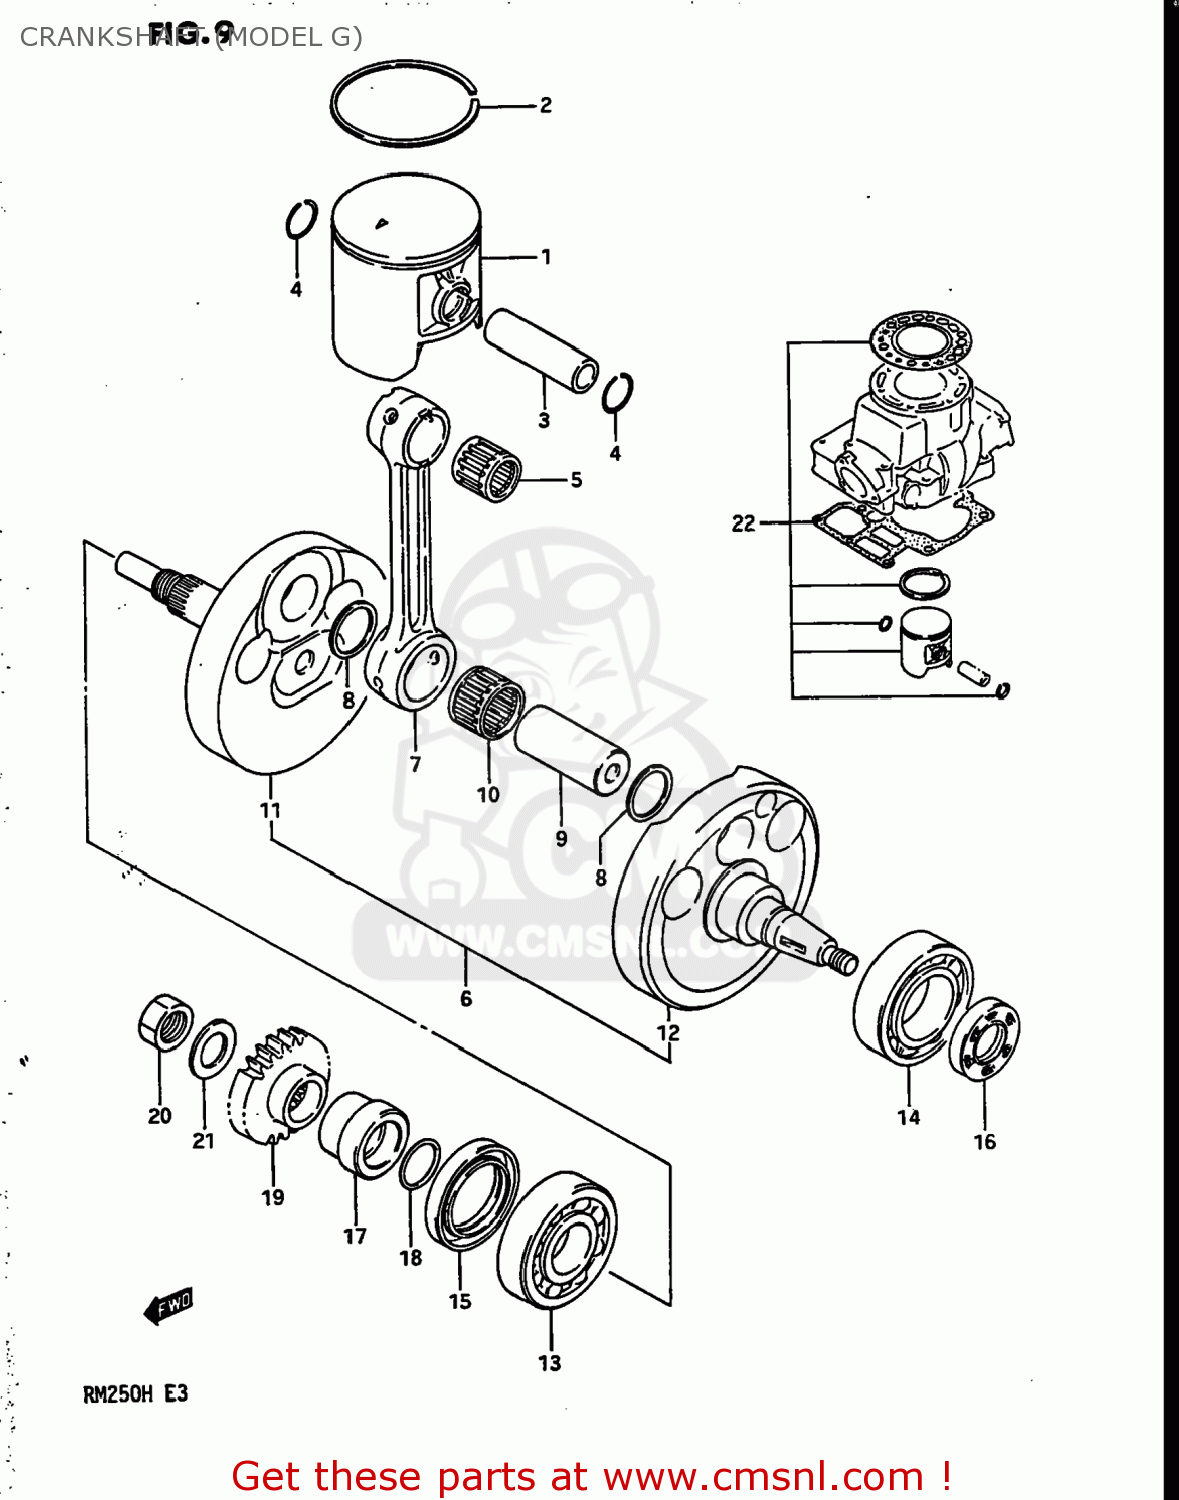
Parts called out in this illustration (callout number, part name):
1	PISTON
2	RING,PISTON
3	PIN,PISTON (18MM)
4	CIRCLIP
5	BEARING(18X23X22)
6	CRANKSHAFT ASSEMBLY
7	CONNECTION ROD
8	WASHER(24X29X1.5)
9	PIN,CRANK
10	BEARING
11	CRANKSHAFT,RIGHT
12	CRANKSHAFT,LEFT
13	BEARING(25X62X17)
14	BEARING(30X62X16)
15	SEAL,OIL(36X52X8)
16	OIL SEAL
17	SPACER,PRIMARY DRIVE GEAR
18	O RING(D:2.4,ID:21.8)
19	GEAR,PRIMARY DRIVE
20	NUT
21	WASHER
22	TOP END KIT,ENGINE
